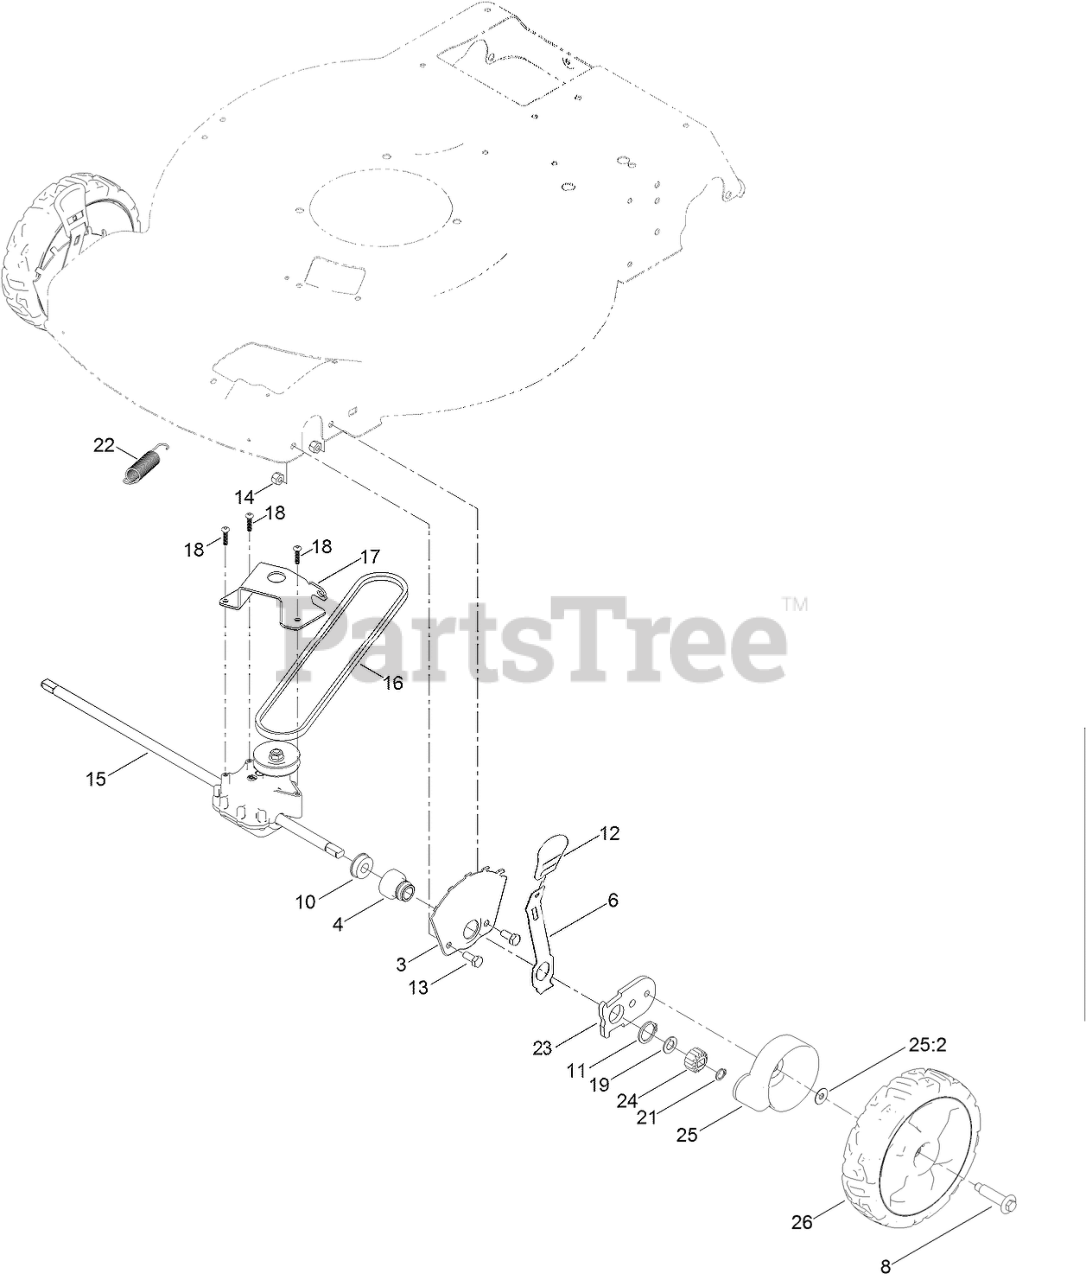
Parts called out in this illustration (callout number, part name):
3	PLATE-HOC, FRONT
4	RETAINER-BEARING, HOC
6	Arm-Spring
8	BOLT-SHOULDER
10	BEARING-BALL
11	RING-RETAINING
12	KNOB-HOC
13	SCREW-HH
14	NUT-LOCK, NI
15	TRANSMISSION ASM
16	V-BELT
17	BRACKET-TRANSMISSION
18	SCREW-PLASTITE
19	WASHER-THRUST
21	RING-RETAINING
22	SPRING EXTENSION
23	ARM-PIVOT, FRONT
24	GEAR-PINION, 15T
25	GEAR COVER ASM
25:2	WASHER-STEPPED
26	8 INCH WHEEL GEAR ASM
